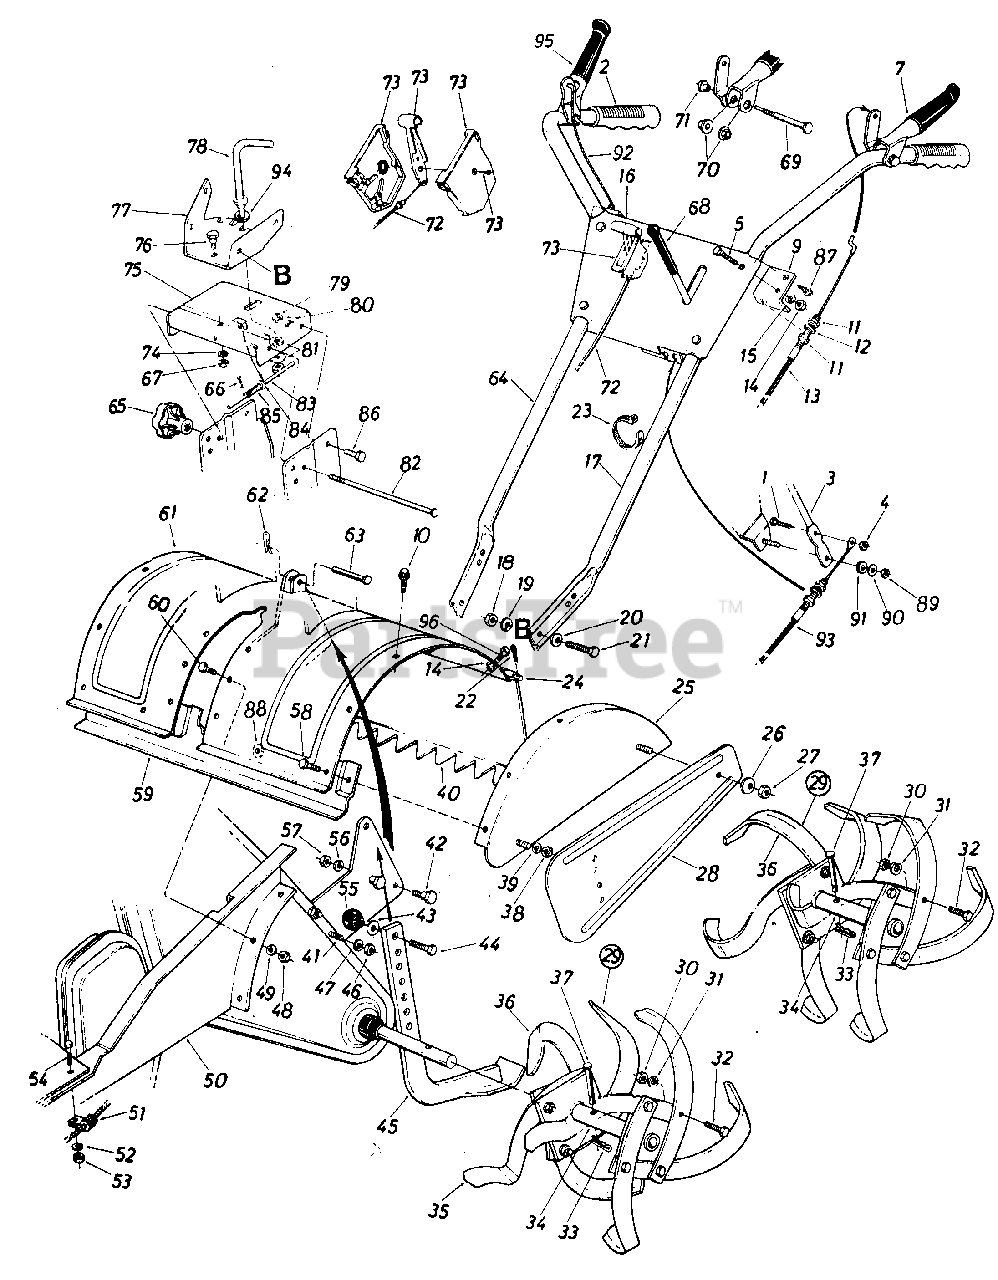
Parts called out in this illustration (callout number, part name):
1	Hex Bolt 1/4-28 x 1.0" Lg.
2	Grip
3	Clutch Lever
4	Hex Cent. L-Nut 1/4-28 Thd.
5	Carr. Bolt 5/16-18 x 1.75"*
7	Clutch Grip Ass'y.L.H.
9	Clutch Cable Bracket
10	Hex Wash. S-Tap Scr. 5/16-18 x .62" Lg.
11	Hex Nut 5/16-24 Thd.
12	L-Wash. 5/16" I.D.
13	Clutch Control Cable
14	Hex Nut 5/16-18 Thd.
15	L-Wash. 5/16" I.D.
18	Hex Nut 3/8-16 Thd.*
19	L-Wash. 3/8" I.D.
20	Bell-Wash. 3/8" I.D.
21	Hex Bolt 3/8-16 x 1.00" Lg.
22	Coter Pin 3132" Dia. x 3/4"
23	Cable Tie
24	Tiller Flap Rod
27	Hex Nut 5/16-18 Thd.
30	Hex Nut 3/8-24 Thd.
31	L-Wash. 3/8" I.D.
32	Hex Bolt 3/8-24 x 1.25" Lg.
33	Hairpin Coter
38	Hex Nut 5/16-18 Thd.
39	L-Wash. 5/16" I.D.
41	Hex Bolt 5/16-18 x 1.0" Lg.
42	Shld. Bolt 1/2" Dia. x .426"
43	Fl-Wash. 3/8" I.D. x 518" O.D.
44	Hex Bolt 3/8-16 x 3/4" Lg.
46	Hex Nut 5/16-18 Thd.*
47	L-Wash. 5/16" I.D.
48	Hex Nut 5/16-18 Thd.
49	L-Wash. 5/16" I.D.
52	L-Wash. 5/16" I.D.
53	Hex Nut 5/16-18 Thd.
54	Hex Bolt 5/16-18 x 3/4" Lg.
55	Ball Knob 11/4" Dia.
56	L-Wash. 3/8" I.D.
57	Hex Nut 3/8-16 Thd.*
58	Hex Bolt 5/16-18 x .75" Lg.
60	Hex Bolt 5/16-18 x .75" Lg.
62	Hairpin Coter
63	Clevis Pin 3/8" Dia.
64	Handle-R.H.
65	Hand Knob
66	Coter Pin 1/16" Dia. x .75"
67	Hex Cent. L-Nut 3/8-16 Thd.
69	Shoulder Bolt .375" Dia. x 1.37" Lg.
70	Hex Flange Plastic Bearing
71	Shoulder Nut 1/4-20 Thd.
72	Throttle Control Wire
73	Throttle Control Box Ass'y.
74	Bell-Wash. .40" I.D. x 1.13"
79	Hex Cent. L-Nut 3/8-16 Thd.
80	Bell-Wash. .40" I.D. x .88"
81	Bell-Wash. 1/2" I.D. x 1.00"
82	Lock Pin 5/16" Dia. x 8"
83	Lower Sliding Ass'y.
84	Fl-Wash. .291" I.D. x .62"
85	Compression Spring .36" O.D. x 1.00" Lg.
86	Shoulder Bolt 1/2" Dia. x . 170" Lg.
87	Hex Wash. S-Tap Scr. 1/4-20 x .50" Lg.
88	Bell-Wash. 5/16" I.D.
89	Hex Cent. L-Nut 5/16-18 Thd.
90	Fl-Wash. .344" I.D. x .87"
91	Rubber Wash. .33 I.D. x .87"
92	Control Cable
93	Control C'able
94	Fl-Wash. .62" I.D. x 1.57"
95	Clutch Grip Ass'y.R.H.
96	Hex Bolt 5/16-18 x 1.25"
